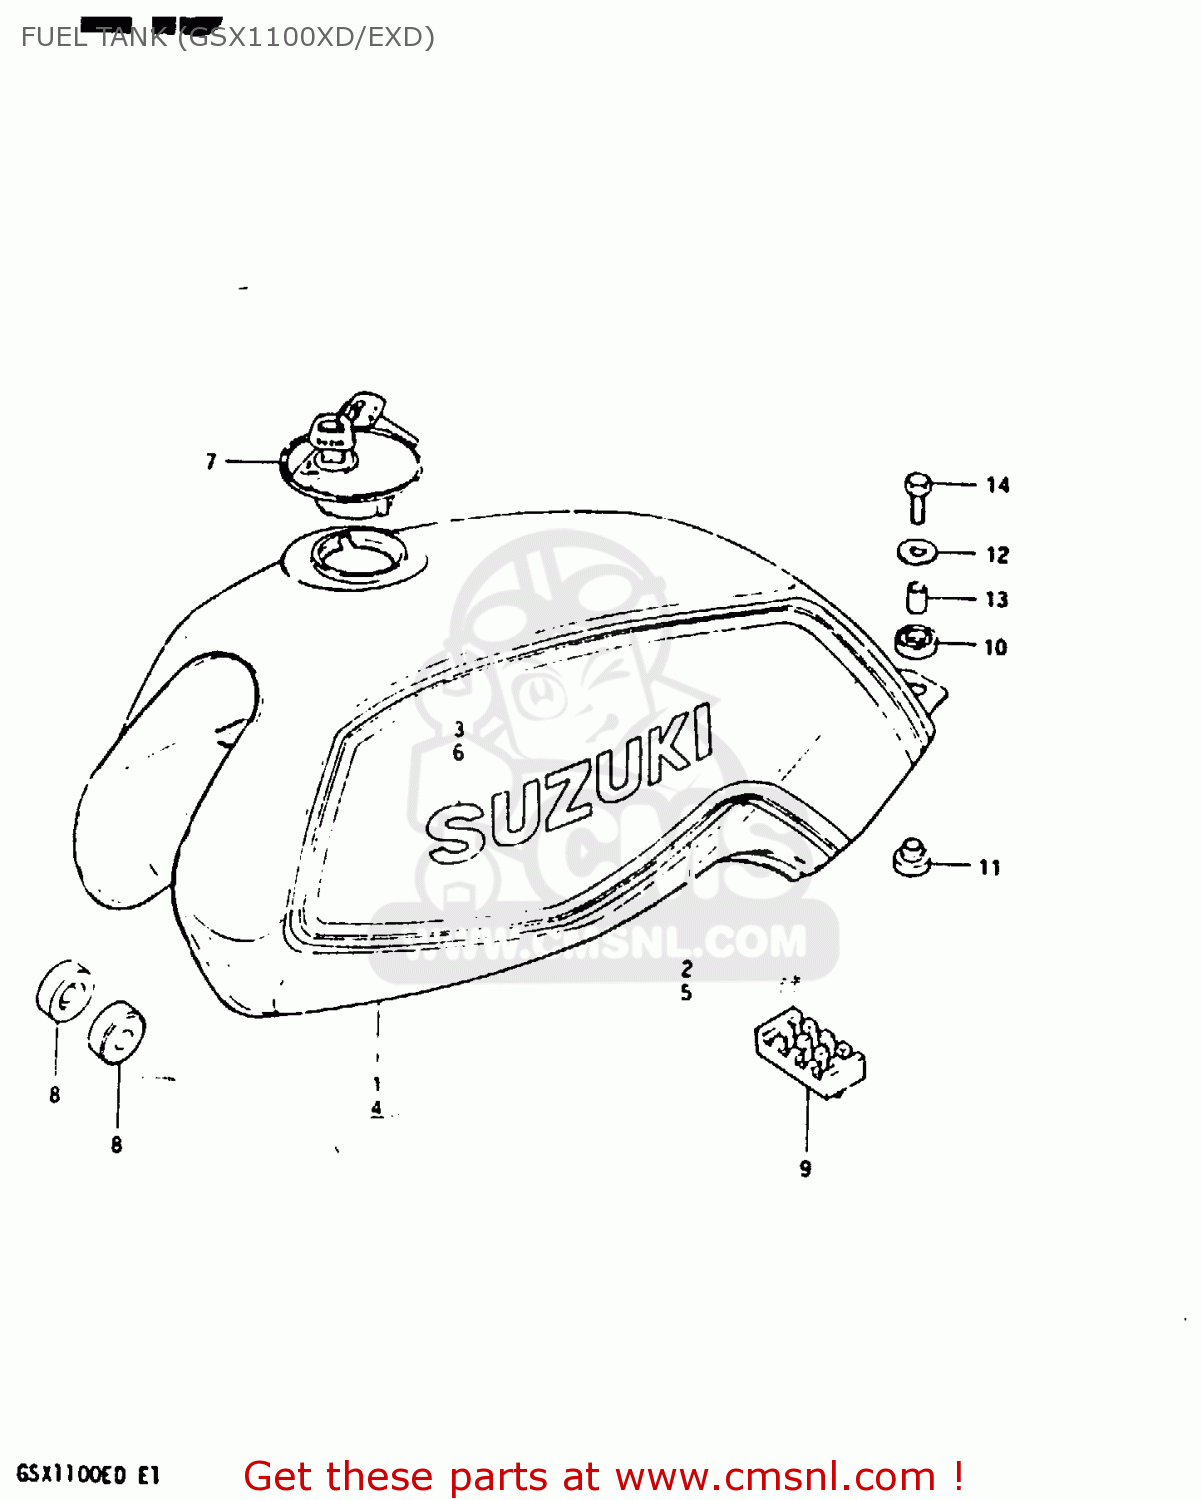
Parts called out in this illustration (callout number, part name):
1	TANK SET, FUEL
2	TAPE SET, FUEL TANK
3	EMBLEM,FUEL TANK
4	TANK SET, FUEL (RED)
5	TAPE SET, FUEL TANK
6	EMBLEM(SILVER)
7	CAP SET,FUEL TANK
8	CUSHION
9	CUSHION,FUEL TANK CTR
10	CUSHION
11	CUSHION
12	WASHER (6.5X24X1.6)
13	SPACER
14	BOLT
